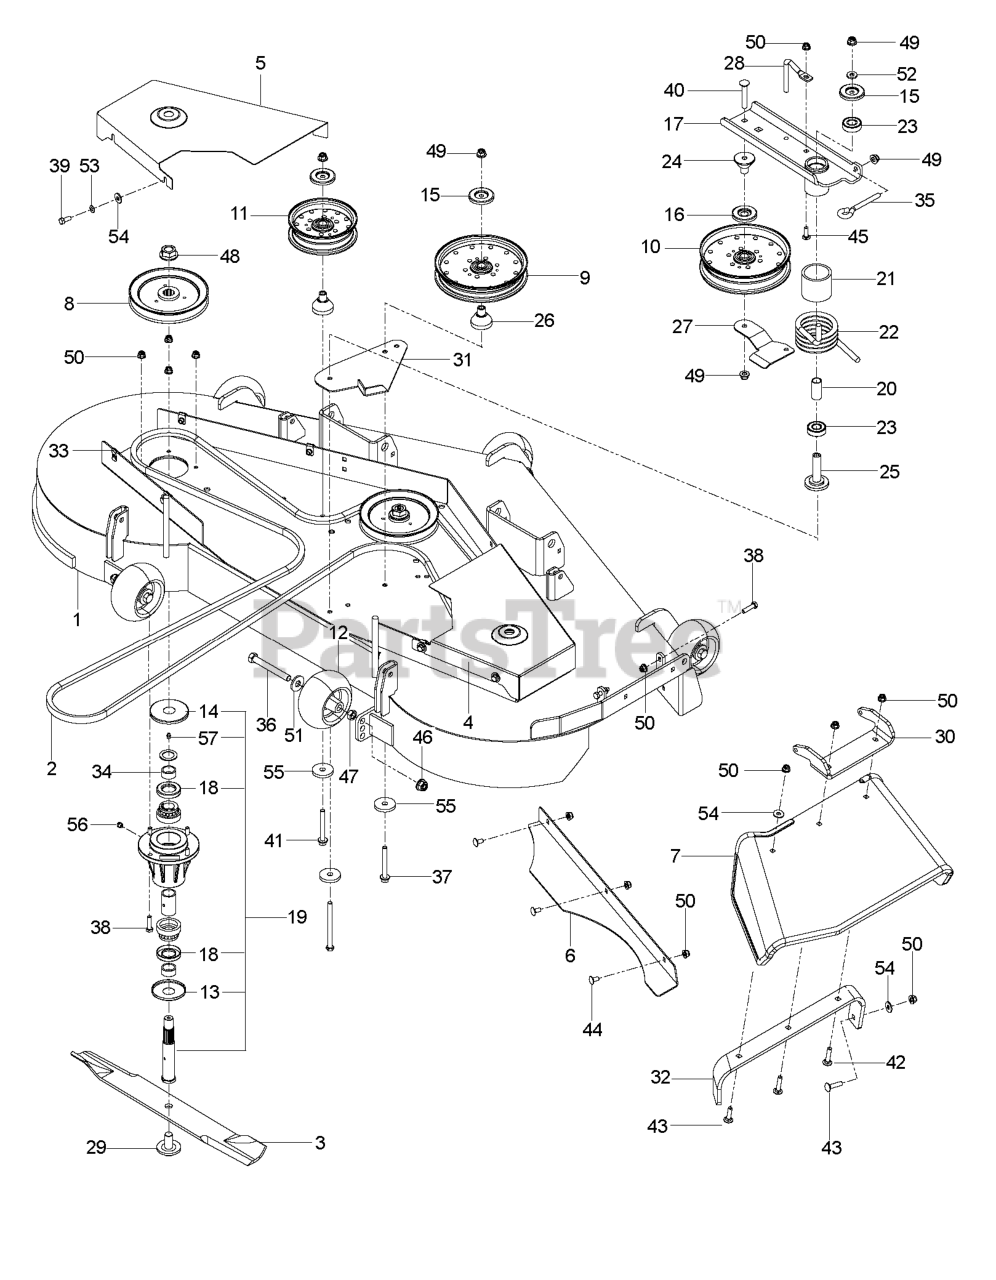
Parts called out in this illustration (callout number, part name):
1	DECK.SVC.W/DECALS.61.PZT.ORNGE
3	BLADE - HEAVY DUTY 21"
4	SHIELD BELT RH 61" ORANGE
5	SHIELD BELT LH 61" ORANGE
6	CONFINEMENT PLATE 61
7	CHUTE, RUBBER DISCHARGE 52/61"
8	PULLEY, 61
9	PULLEY - IDLER 7"
10	PULLEY - 7" NARROW
11	IDLER PULLEY
12	GAUGE WHEEL
13	BOTTOM DUST CAP
14	TOP DUST CAP
15	DUST SHIELD
16	SHIELD, DUST
17	IDLER.ARM.BLACK
18	SHAFT SEAL
19	HOUSING ASM, 52/61
20	SPACER, IDLER BEARINGS
21	SPACER, IDLER PIVOT
22	SPRING, TORSION, IDLER
23	BEARING, BALL
24	BEARING, IDLER ARM
25	BEARING, IDLER PIVOT
26	BEARING, IDLER STANDOFF
27	BELT.GUIDE.BLACK
28	BELT KEEPER
29	BLADE BOLT/WASHER
30	PIVOT BRACKET - CHUTE
31	BRACKET, SPRING STOP
32	BRKT, REINF - CHUTE 52/61"
33	U-CLIP 5/16-18 NUT RETAINER
34	MACHINE BUSHING
35	EYE BOLT, 3/8 X 4"
36	HCS 1/2-13 X 4 GR 5 ZD
37	HCS 3/8-16 X 4-1/2 GR 8 ZD
38	HCS 5/16C X 1 1/4
39	HCS 5/16C X 3/4
40	CARRIAGE BOLT 3/8-16 X
41	HHFS 3/8-16 X 3 GRD 5 ZD
42	RHSNB 5/16-18 X 1-1/2 GR 5 ZD
43	BOLT, CARRIAGE 5/16X1-1/4
44	CARRIAGE BOLT 5/16C X 5/8"
45	RHSSNB 5/16C X 1.0
46	NUT, 1/2-13 HEX FLG NYLOC ZD
47	NUT 1/2 HEX JAM
48	NUT FLANGE 3/4-16
49	NUT 3/8-16 HEX FLG NYLOC ZD
50	5/16-18 NYLOC FLANGE NUT
51	WASH USS FLAT 1/2
52	WASHER, 3/8 THICK
53	WASH 5/16 DISC SPRING ZD
54	WASHER 5/16 FLAT
55	SPINDLE WASHER
56	PLUG-VENTED
57	ZERK
